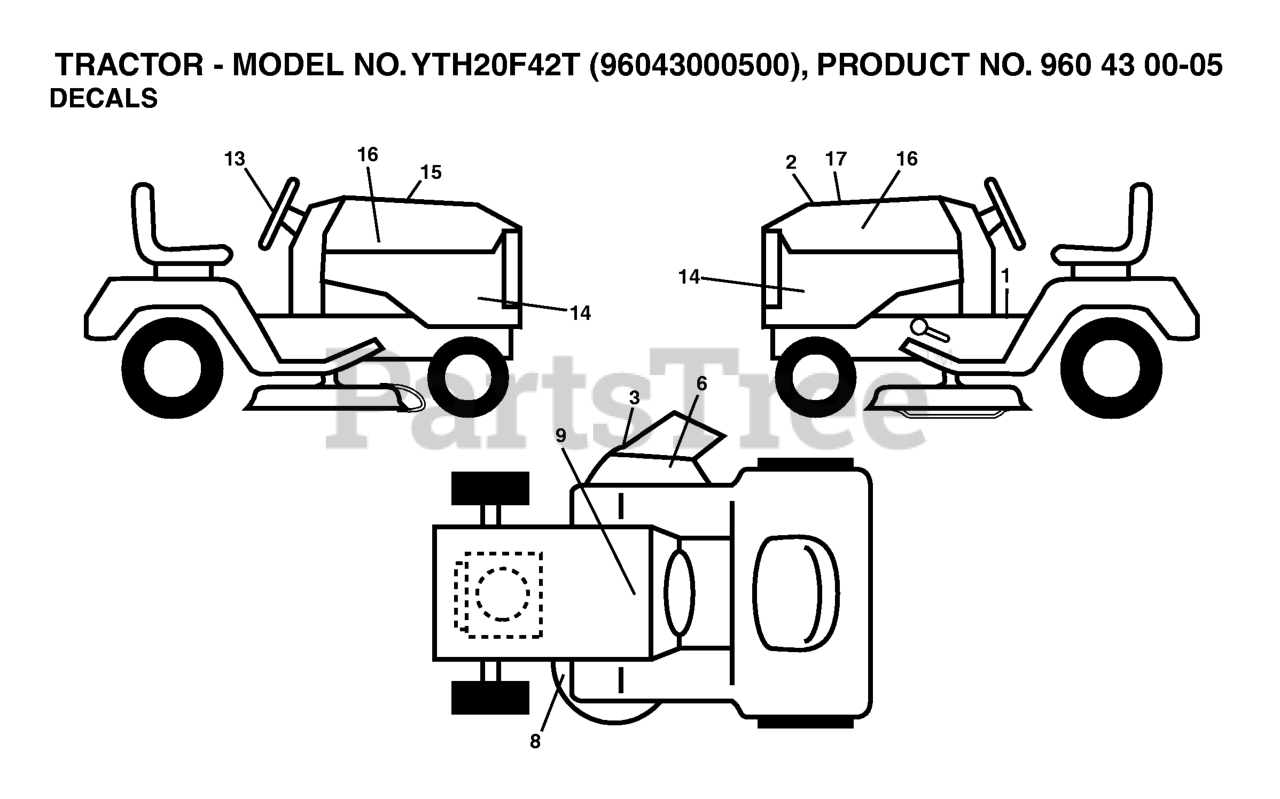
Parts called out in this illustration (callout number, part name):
2	DECAL.HOOD.TOP.INSERT.
3	DECAL.WARN.KEEP.HAND.AWAY
6	DECAL DECK "B" 42"
8	DECAL V BELT SCHEMATIC
9	DECAL BTRY SYMBOLS
13	DECAL.STEERING.HUSQ.BLUE
15	DECAL HOOD CUST. RESP.
16	DECAL.HOOD.NAMELOGO.HUSQ
